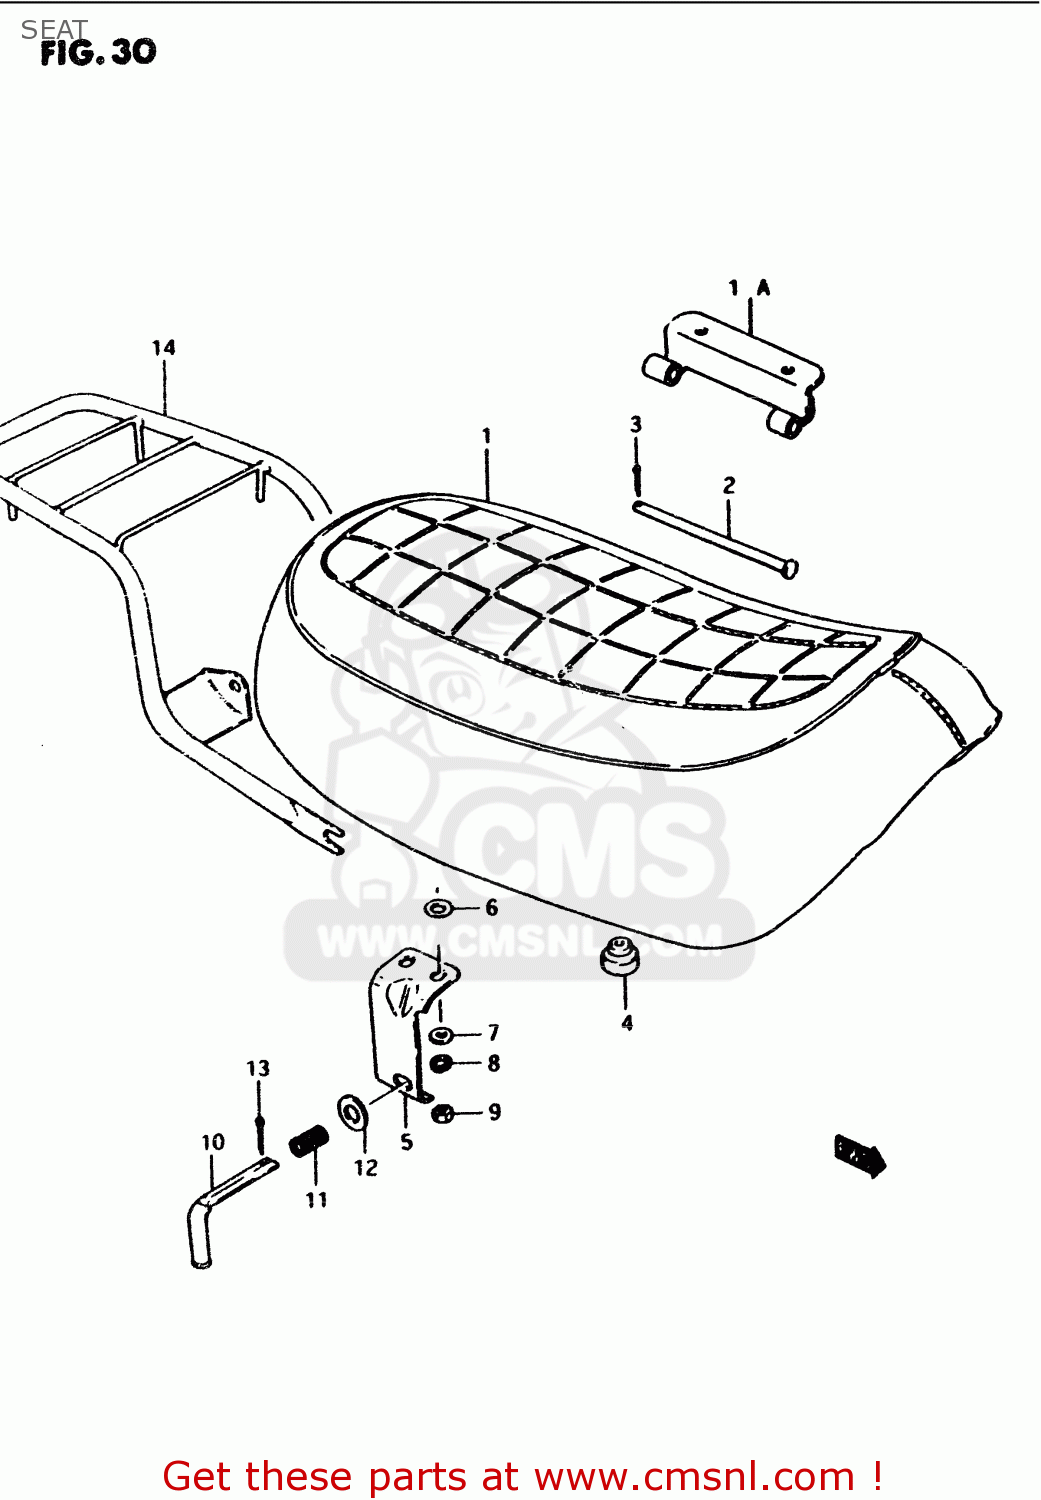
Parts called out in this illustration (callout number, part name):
1	SEAT (BLACK)
1A	PLATE,SEAT SUPPORT
2	PIN
3	PIN
4	CUSHION
5	PLATE,CLAMP GUIDE
6	WASHER
7	WASHER
8	WASHER,LOCK
9	NUT
10	BAR, SEAT CLAMP
11	SPRING
12	WASHER (9.5X20X1)
13	PIN 20X20
14	CARRIER,SPORT
